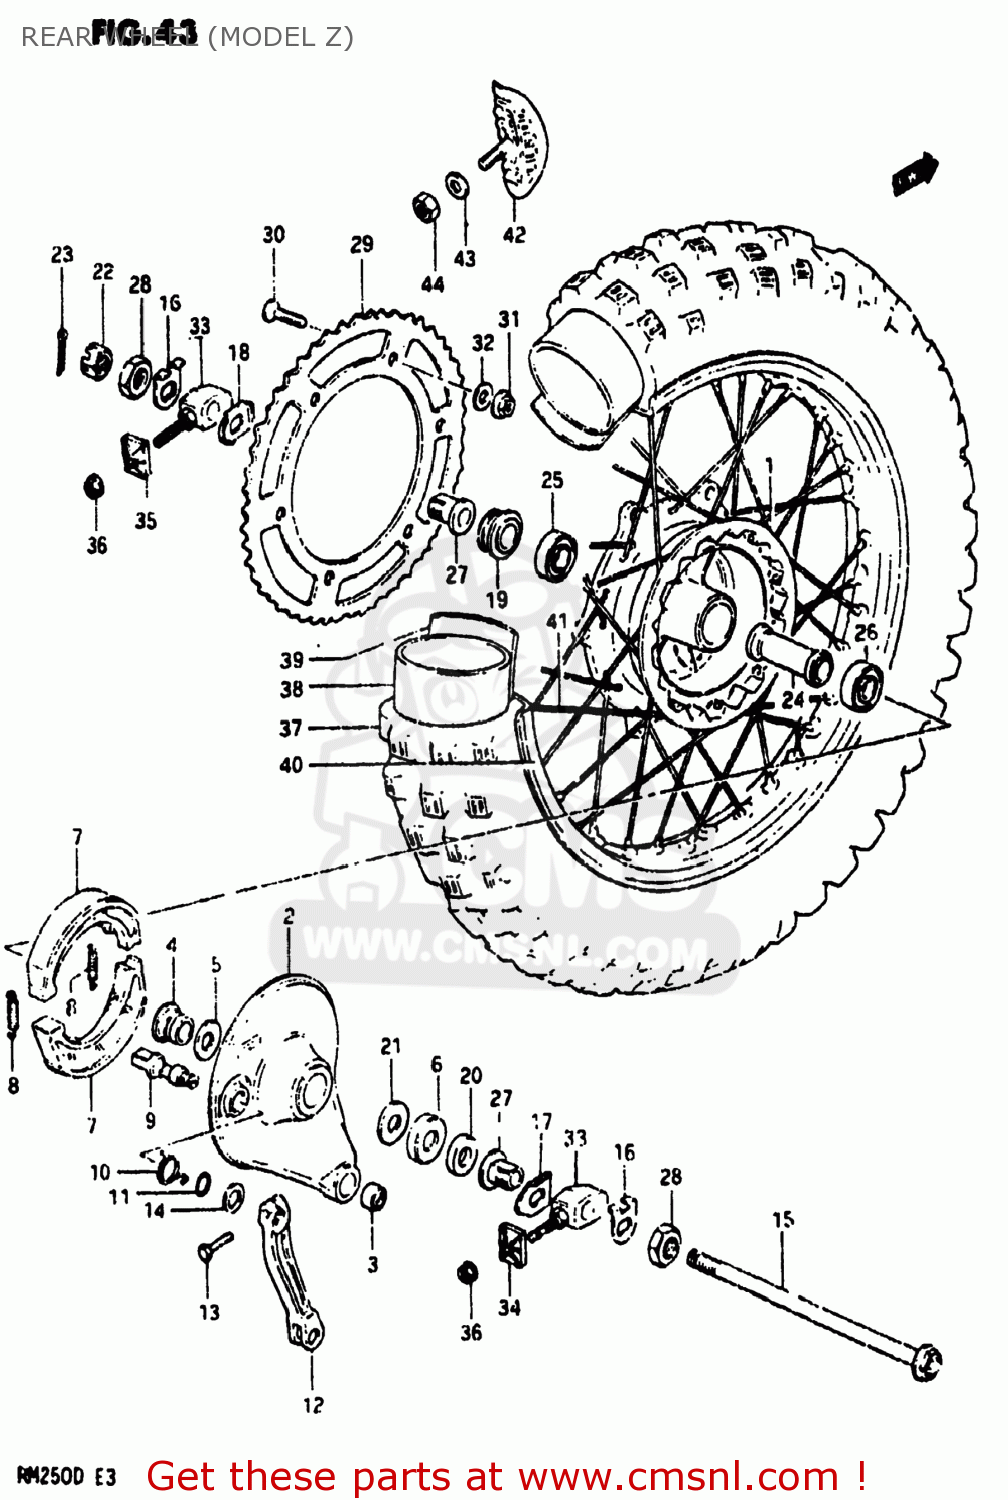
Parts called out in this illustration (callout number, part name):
1	DRUM,REAR HUB
2	PANEL SET,REAR HUB
3	SPHERICAL BRNG,TORQUE LINK
4	SPACER,RR BRAKE ANCHOR PANEL
5	SEAL,OIL(20X27X5)
6	CVR,RR BRAKE AHR PNL DUST SEAL
7	SHOE,BRAKE (MCA)
8	SPRING(L:34)
9	CAM,FR BRAKE
10	SPRING
11	O RING(D:2.5,ID:11.4)
12	LEVER,RR BRAKE CAM
13	BOLT
14	WASHER(12.5X20X1)
15	AXLE,REAR
16	WASHER,CHAIN ADJUSTER
17	PLATE,CHAIN ADJUSTER,RIGHT
18	PLATE,CHAIN ADJUSTER,LEFT
19	SPACER,RR AXLE,L
20	SPACER,REAR AXLE,RIGHT
21	WASHER,THRUST
22	NUT
23	COTTER PIN
24	SPACER
25	BEARING
26	BEARING
27	SPACER,CHAIN ADJUSTER
28	NUT
29	SPROCKET,REAR
30	SCREW(8X33.5)
31	NUT
32	WASHER
33	ADJUSTER,CHAIN
34	PLATE,CHAIN ADJUSTER GUIDE,R
35	PLATE,CHAIN ADJUSTER GEAR
36	NUT
37	TIRE
38	TUBE,INNER
39	PROTECTOR,WHEEL,INNER
40	RIM,REAR WHEEL
41	SPOKE SET,REAR WHEEL
42	STOPPER,BEAD
43	WASHER
44	NUT 8MM
